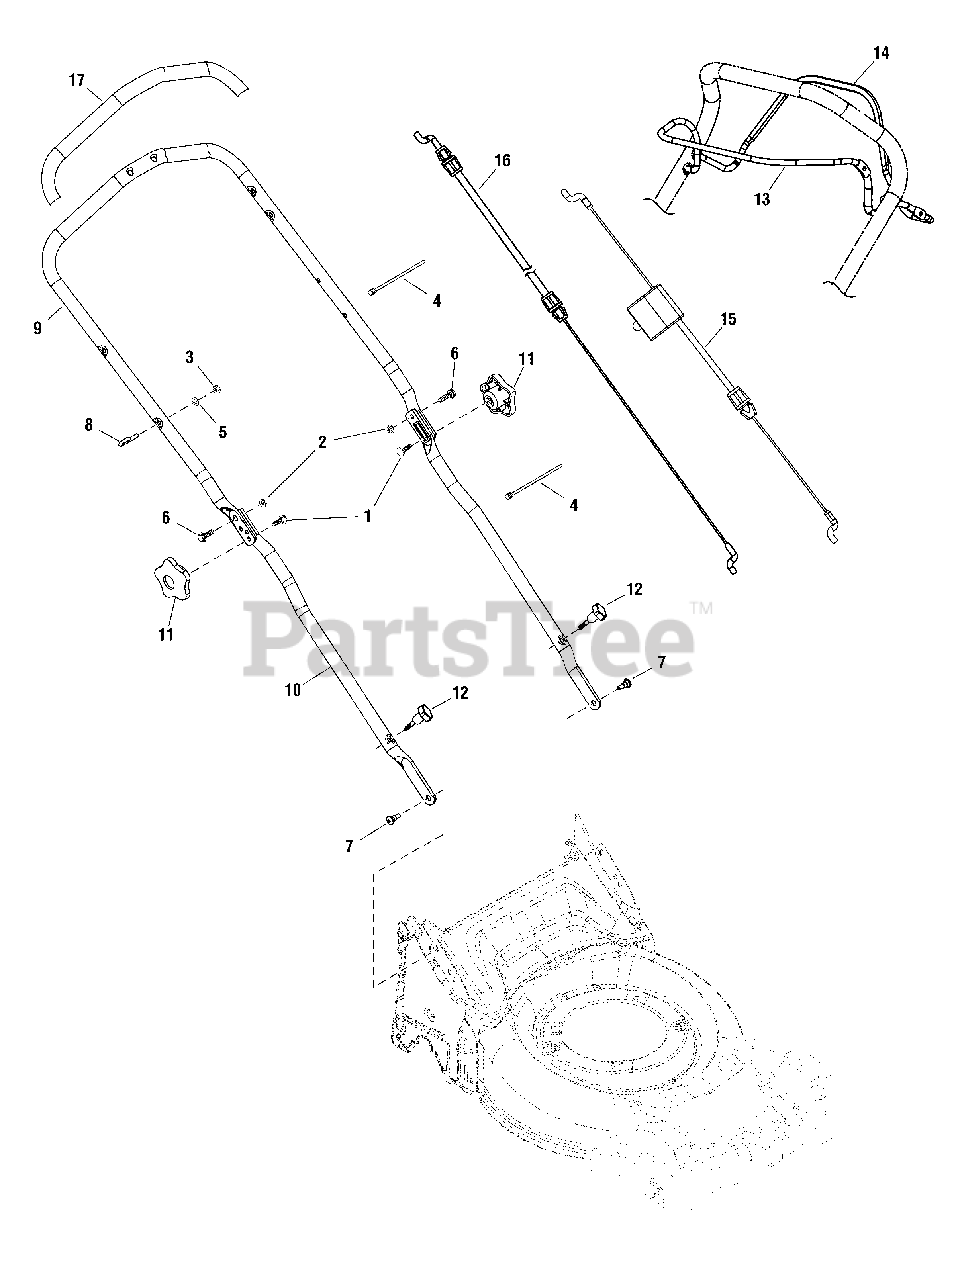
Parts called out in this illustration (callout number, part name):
1	BOLT, 5/16-18 x 1 G5
2	NUT, Nylock Flanged, 1/4-20
3	NUT, Nylock, M6
4	CABLE CLIP
5	WASHER, A6.4
6	SCREW, 1/4-20
7	BOLT, Shoulder
8	BOLT, Eye
9	HANDLE, Upper
10	HANDLE, Lower
11	WING KNOB, 5/16-18
12	WING KNOB
13	BAIL, Control
14	BAIL, Drive
15	CABLE, Drive
16	CABLE, Control
